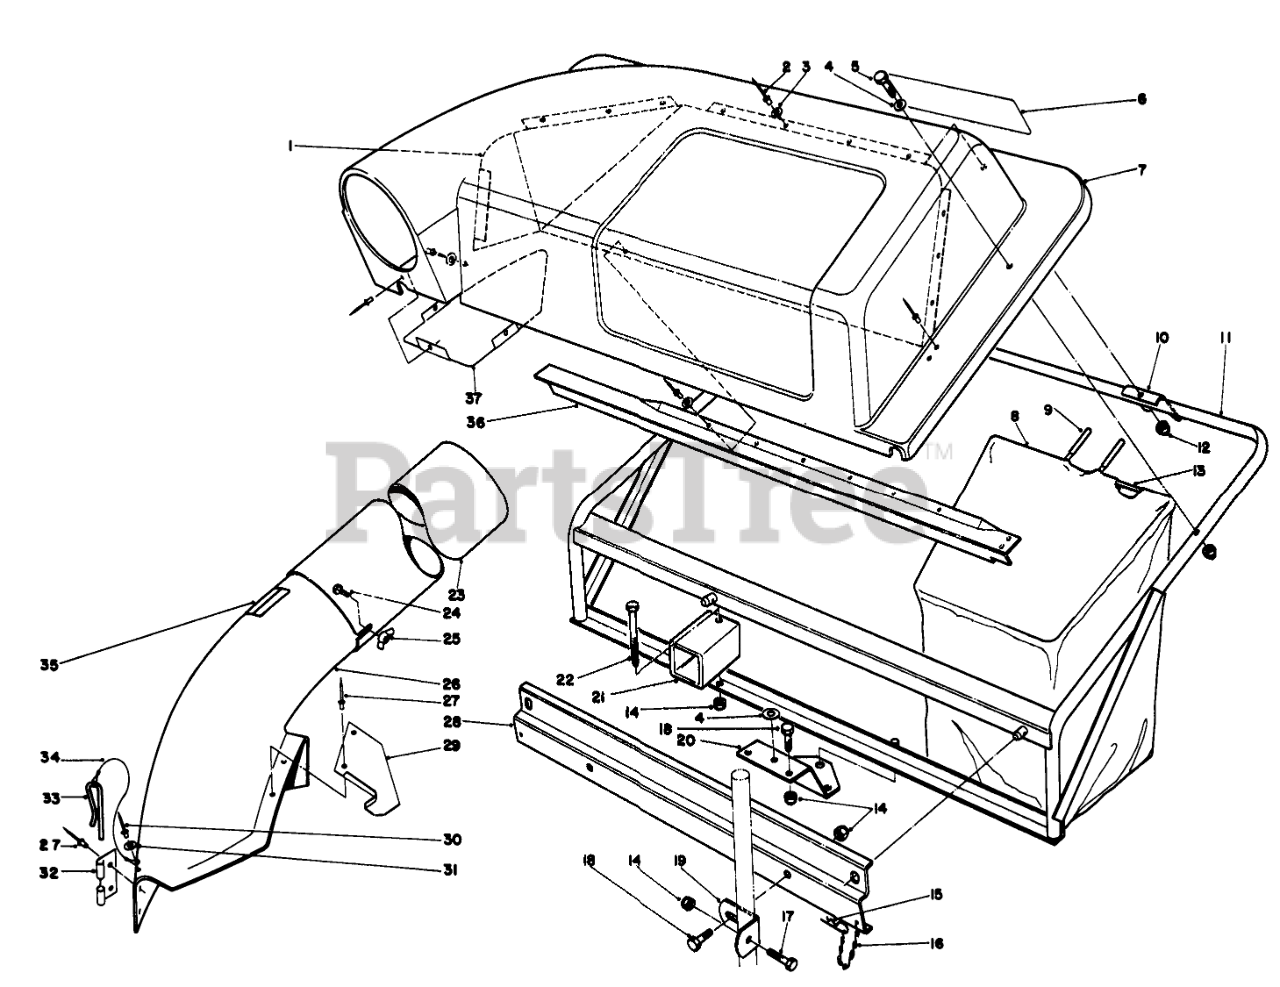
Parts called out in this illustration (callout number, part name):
1	Screen Cover
2	NUT-LOCK
3	WASHER-FLAT
4	WASHER-PLAIN
5	SCREW-HH
6	TWIN BAGGER DECAL
7	Cover
8	Bag-Twin Bagger (Incl. Ret. #9 & 13)
9	GRIP-HANDLE, BAG
10	BAG FRAME BRKT
11	Frame
12	NUT-LOCK, CAP
13	Frame-Bag
14	NUT-LOCK, CONE
15	PIN-HAIR
16	6-LINK CHAIN W/HOOK
17	SCREW-HH
18	SCREW-HH
19	Bracket Mtg. Grass Catcher
20	MTG PLATE B
21	FRAME SUPT TUBE B
22	SCREW-HH
23	TUBE(ROUND&LONG)
24	BOLT-CARR
25	NUT-WING SPECL
26	Chute Assembly (Incl. Ref. #27, 29-35)
27	RIVET-BLIND
28	Bracket Frame Support
29	CHUTE SUPT BRKT
30	RIVET-BLIND
31	WASHER-PLAIN
32	BRACKET-MOUNTING, CHUTE
33	PIN-LOCKING, CHUTE
34	LANYARD
35	DECAL-DANGER
36	SCREEN SUPT BRKT B
37	Shield Cover
